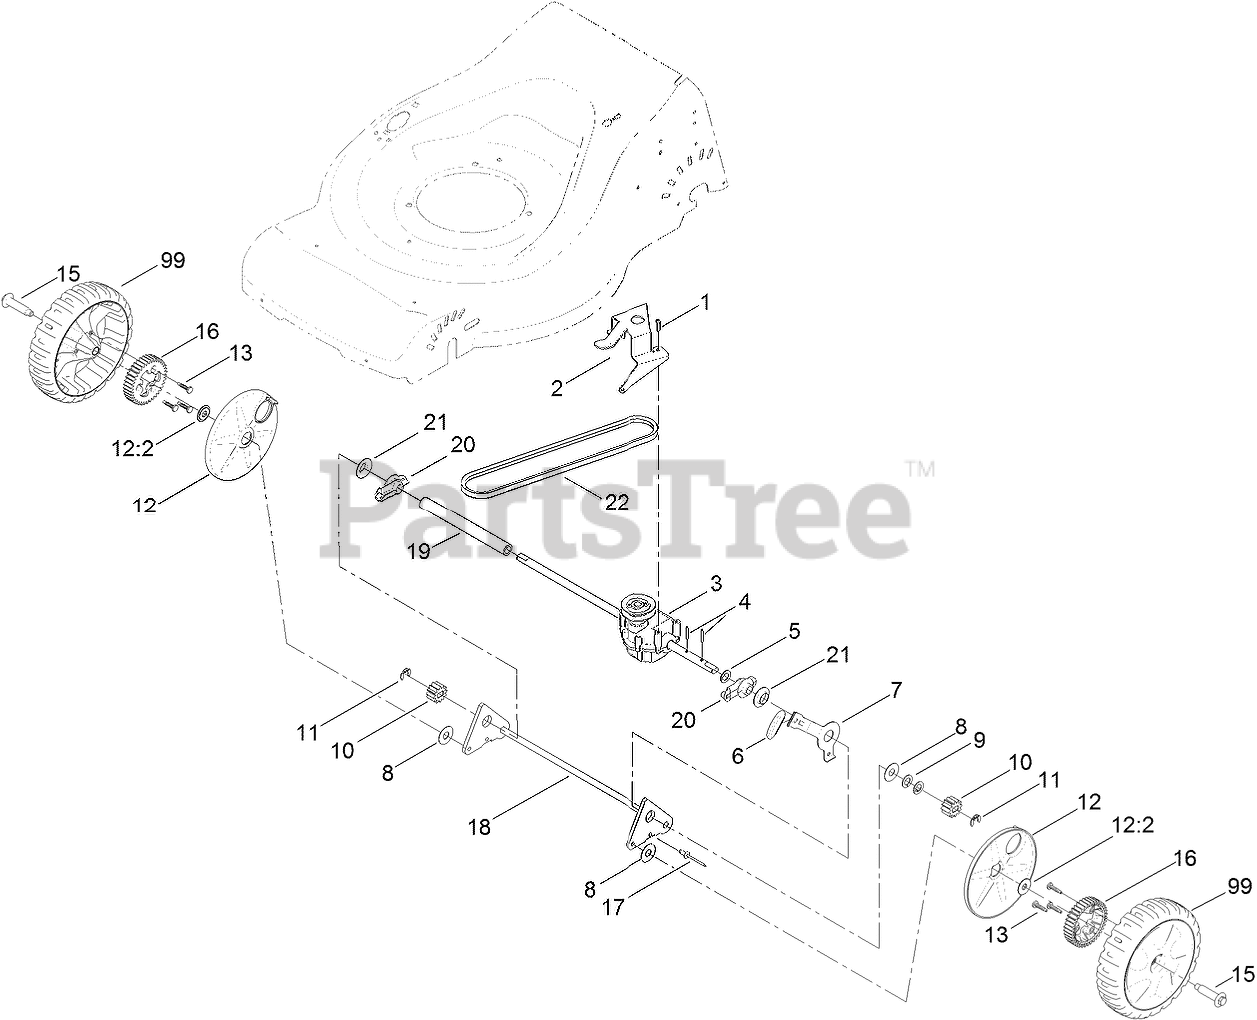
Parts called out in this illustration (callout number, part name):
1	SCREW-TORX, PAN HEAD
2	BRACKET-GEAR CASE
3	TRANSMISSION
4	PIN-ROLL
5	WASHER-THRUST, KEYED
6	KNOB-HOC
7	ARM-SPRING, REAR
8	WASHER-PLAIN
9	WASHER-THRUST
10	GEAR-PINION
11	RING-CLIP, LOCKING
12	WHEEL COVER ASM
12:2	WASHER-STEPPED
13	SCREW-DRIVE
15	BOLT-SHOULDER
16	GEAR-WHEEL, 38T
17	RIVET-POP
18	REAR PIVOT BAR ASM
19	SPACER
20	BUSHING-CAMLOCK
21	SPACER-FLANGE
22	V-BELT
99	8 INCH WHEEL AND GEAR ASM
